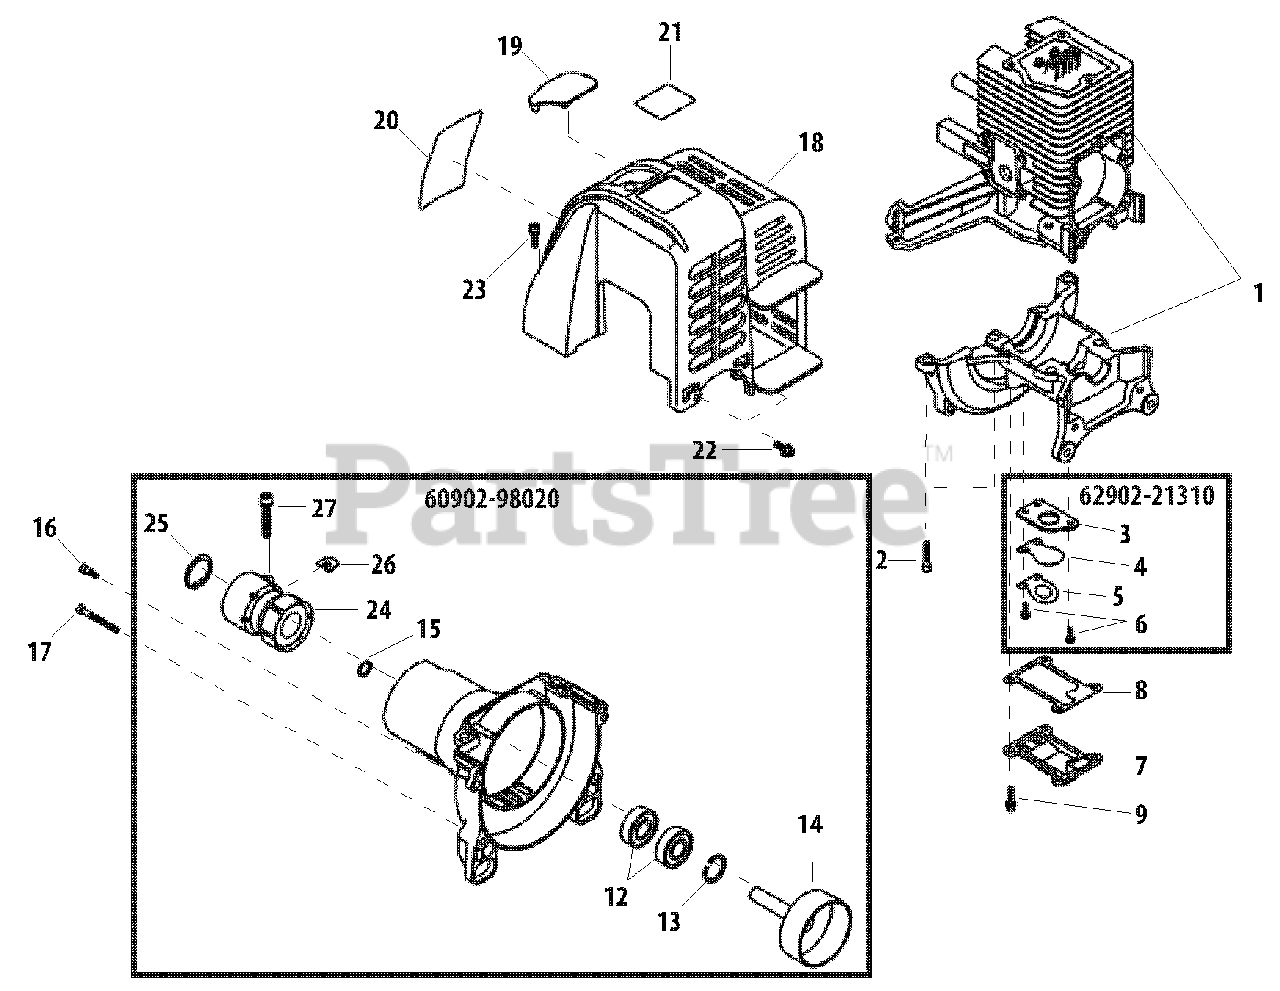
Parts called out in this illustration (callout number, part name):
1	CYLINDER BLOCK SET
2	BOLT 5×16
3	PLATE, REED BACKING
4	VALVE, REED
5	STOP, REED VALVE
6	SCREW M3×10
7	COVER, REED VALVE
8	GASKET, REED VALVE
9	BOLT M4×12
12	BEARING, BALL 6000ZZ
13	RING, SNAP Ø26
14	DRUM, CLUTCH
15	RING, SNAP WR10
16	BOLT 5×16
17	SCREW - 5×35
18	COVER, ENGINE
19	GROMMET
20	LABEL, C4 SHINDAIWA
21	LABEL - TRADE
22	BOLT M4×16
23	BOLT M4×16
24	JOINT
25	RING, SNAP Ø40
26	D-WASHER
27	BOLT M5×22
60902-98020	FAN CASE ASSY
62902-21310	REED VALVE ASSY
